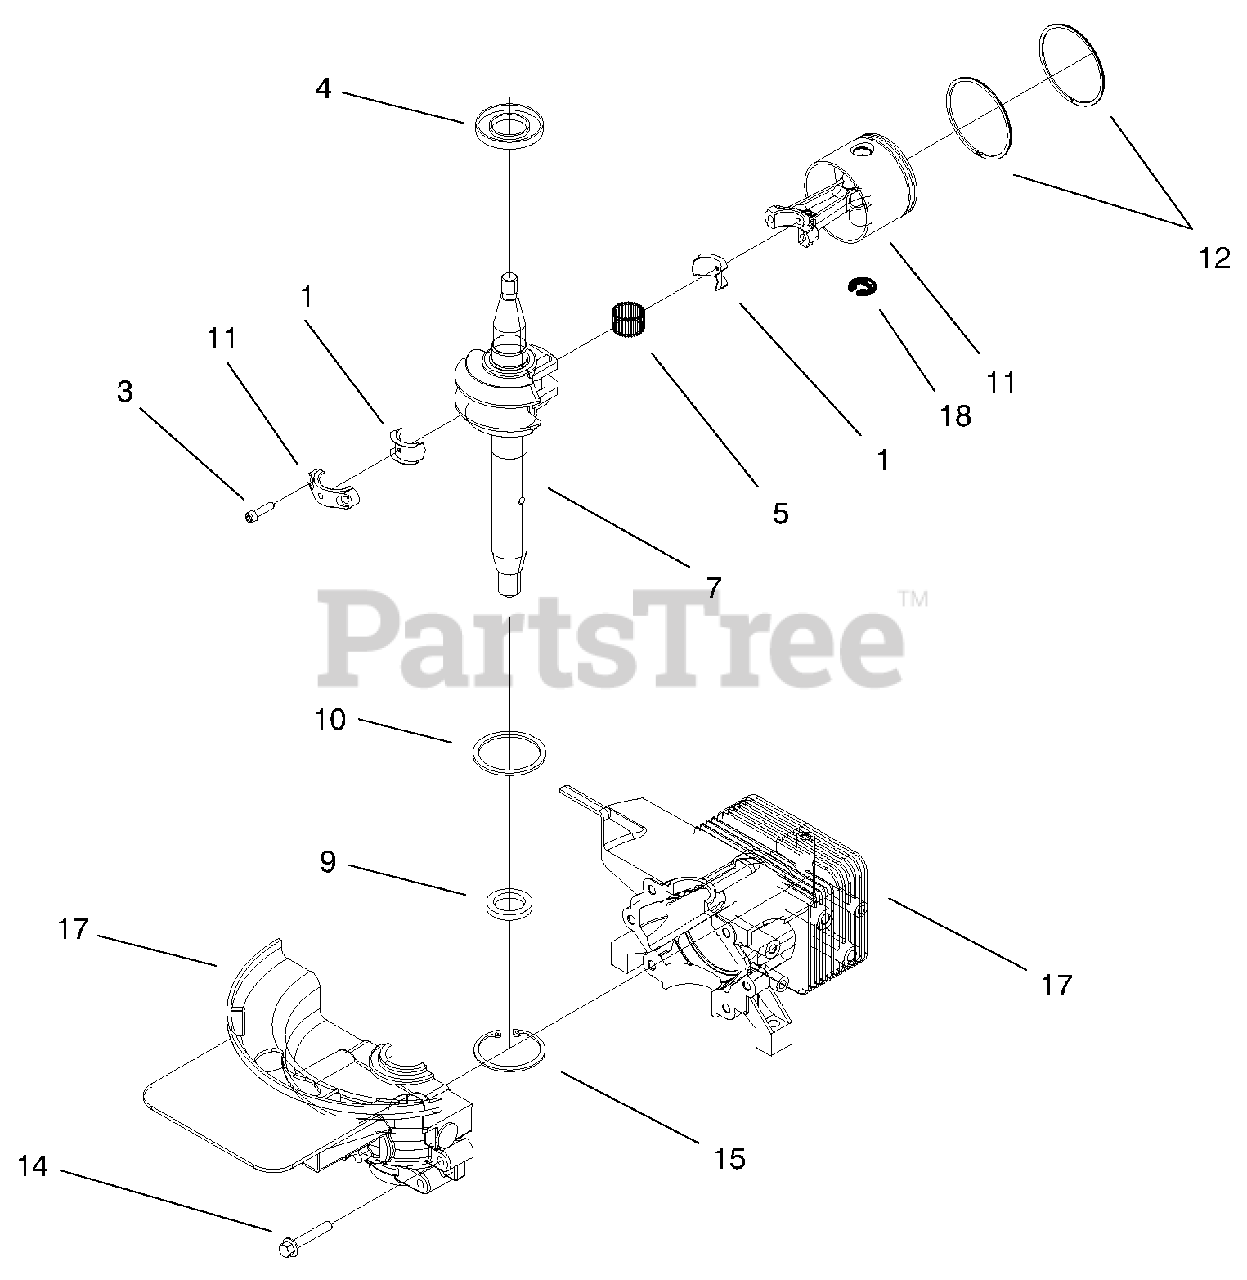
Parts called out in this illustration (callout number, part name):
1	Liner ASM
4	Oil Seal
5	Needle Bearing
7	Crankshaft & Bearing ASM
9	Oil Seal
10	Ring Retaining
11	Piston & Conn Rod ASM
12	Ring Set
14	Screw-HWH
15	Ring-Retaining
16	Connecting Rod ASM
17	Cylinder & Ccase ASM
18	Retaining Ring
